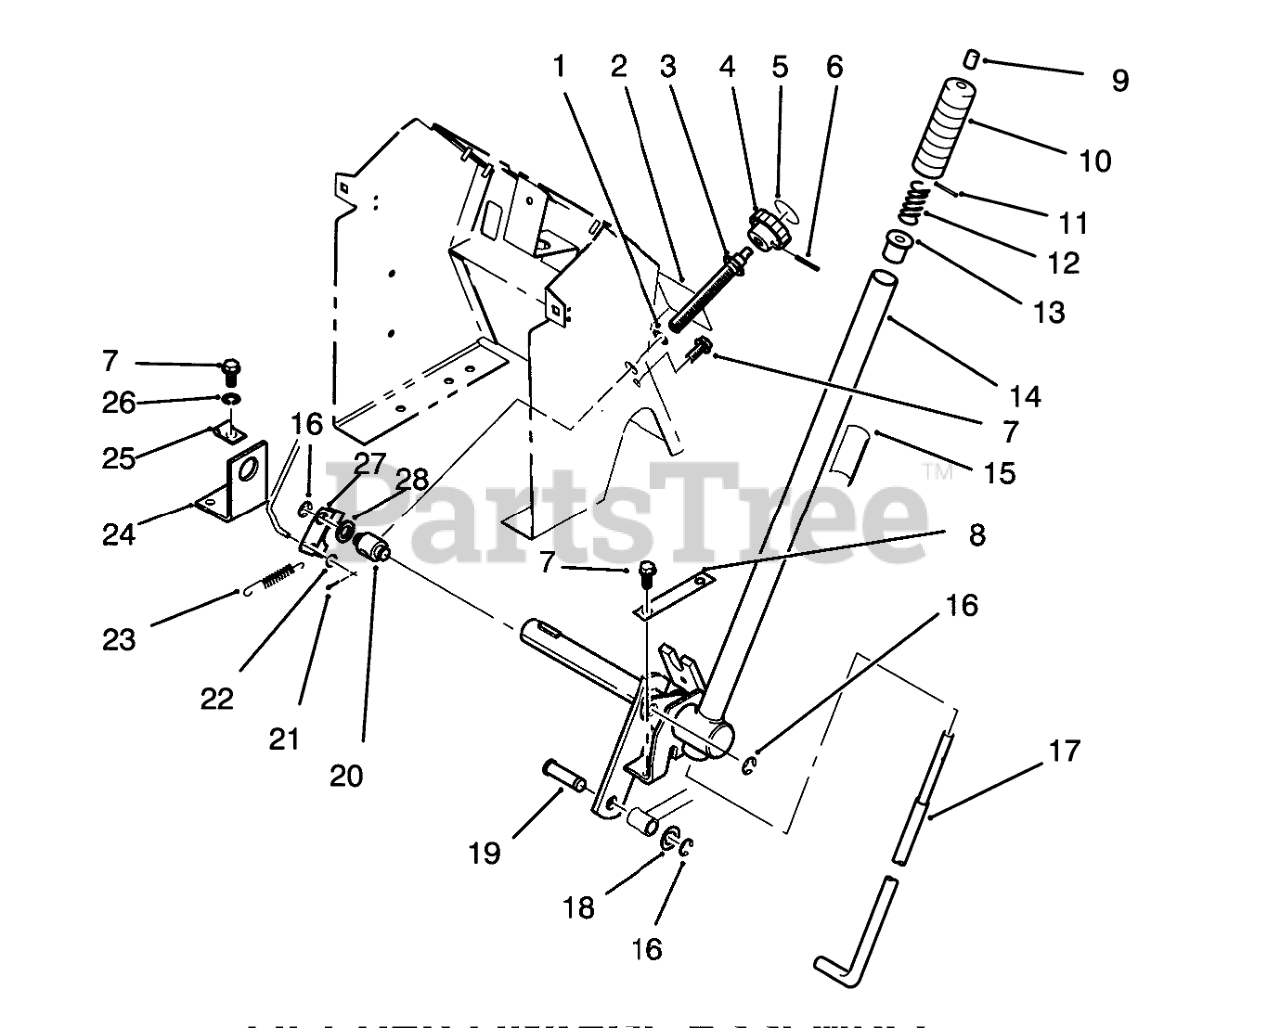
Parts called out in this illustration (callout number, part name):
1	Washer
2	DECAL-LWR HOODSTAND
3	ROD B
5	DECAL-HEIGHT KNOB
6	PIN-SPIROL
7	Screw
8	Plate
9	CAP-ROD, PLUNGER
10	HANDGRIP
11	PIN-SPIROL
12	SPRING-COMPRESSION
13	RETAINER-SPRING
14	WLDMT-LIFT HANDLE B
15	DECAL-LIFT
16	RING-RETAINING, EXTERNAL
17	ROD-LATCH LIFT
18	WASHER-FLAT
19	ASS'Y-WHEEL & TIRE
20	TRUNNION
21	Cotter Pin
22	WASHER-FLAT
23	SPRING-EXTENSION
24	BRACKET B
25	THROTTLE CONTROL CLP
26	Washer-Lock
27	PLATE B
28	Washer
